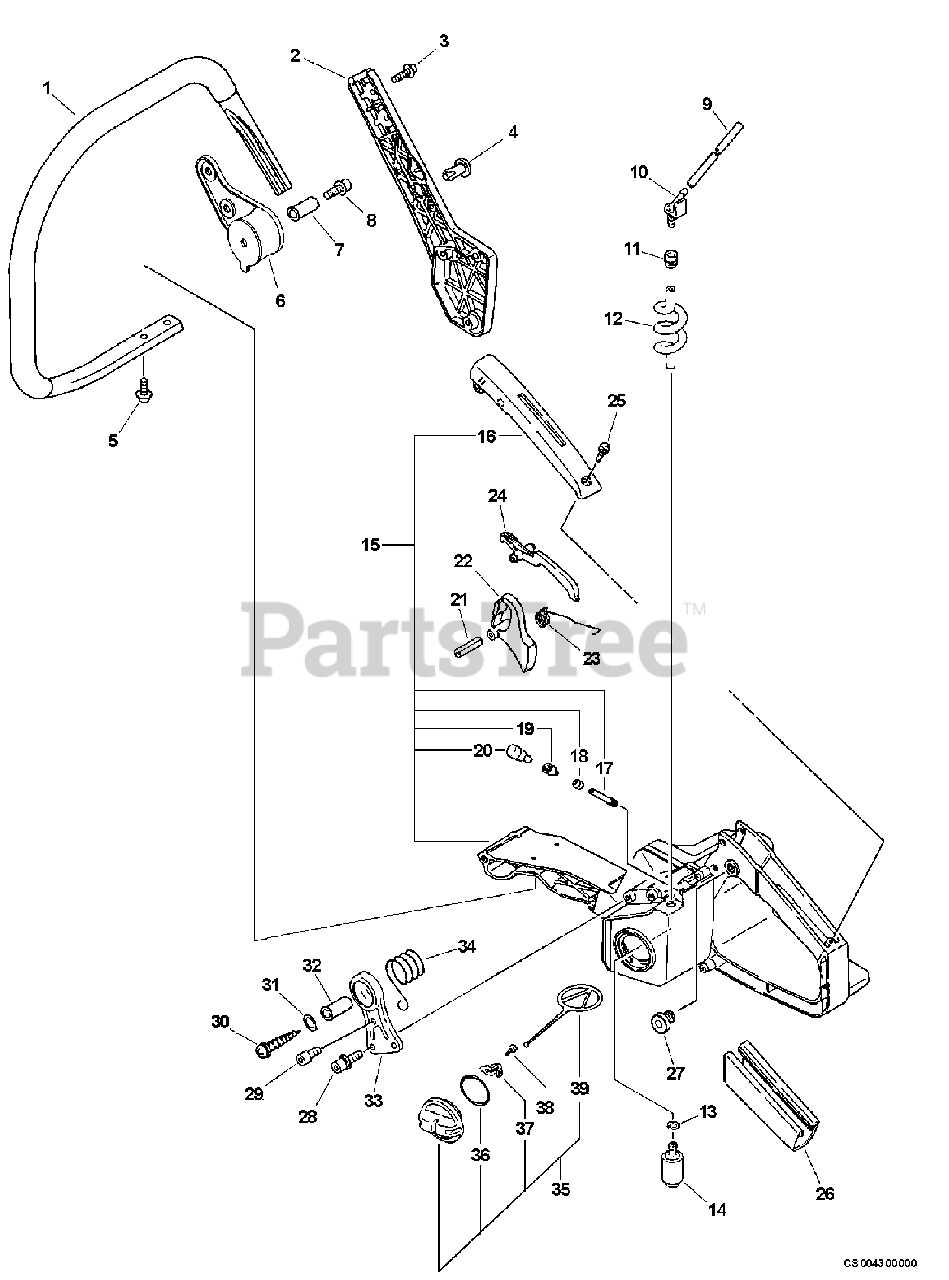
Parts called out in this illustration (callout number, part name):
1	HANDLE, FRONT
2	BRACKET, HANDLE
3	SCREW 5×20
5	BOLT 5×14
6	CUSHION 5
7	COLLAR 5
8	BOLT 5×20
9	PIPE, FUEL 3×6×110
10	CONNECTOR, PIPE
11	GROMMET
12	PIPE, FUEL
13	CLIP Ø6.5 MM
14	FILTER, FUEL
15	HANDLE ASSY, REAR
16	COVER, HANDLE
17	PIPE, VENT
19	HOLDER, VENT
20	VENT ASSY
21	PIN, SPRING Ø5×25 MM
22	TRIGGER, THROTTLE
23	SPRING, THROTTLE RETURN
24	LEVER, THROTTLE LOCKOUT
25	SCREW 4×14
26	GRIP, HANDLE
28	BOLT 5×14
29	BOLT 5×8
30	SCREW - 5×35
31	WASHER 5
32	COLLAR 5
33	BRACKET, CUSHION
34	SPRING, COMPRESSION
35	CAP ASSY, FUEL
36	O-RING 29
37	RETAINER, CONNECTOR
38	SCREW, TAPPING 3×8
39	CONNECTOR, CAP L= 60 MM
